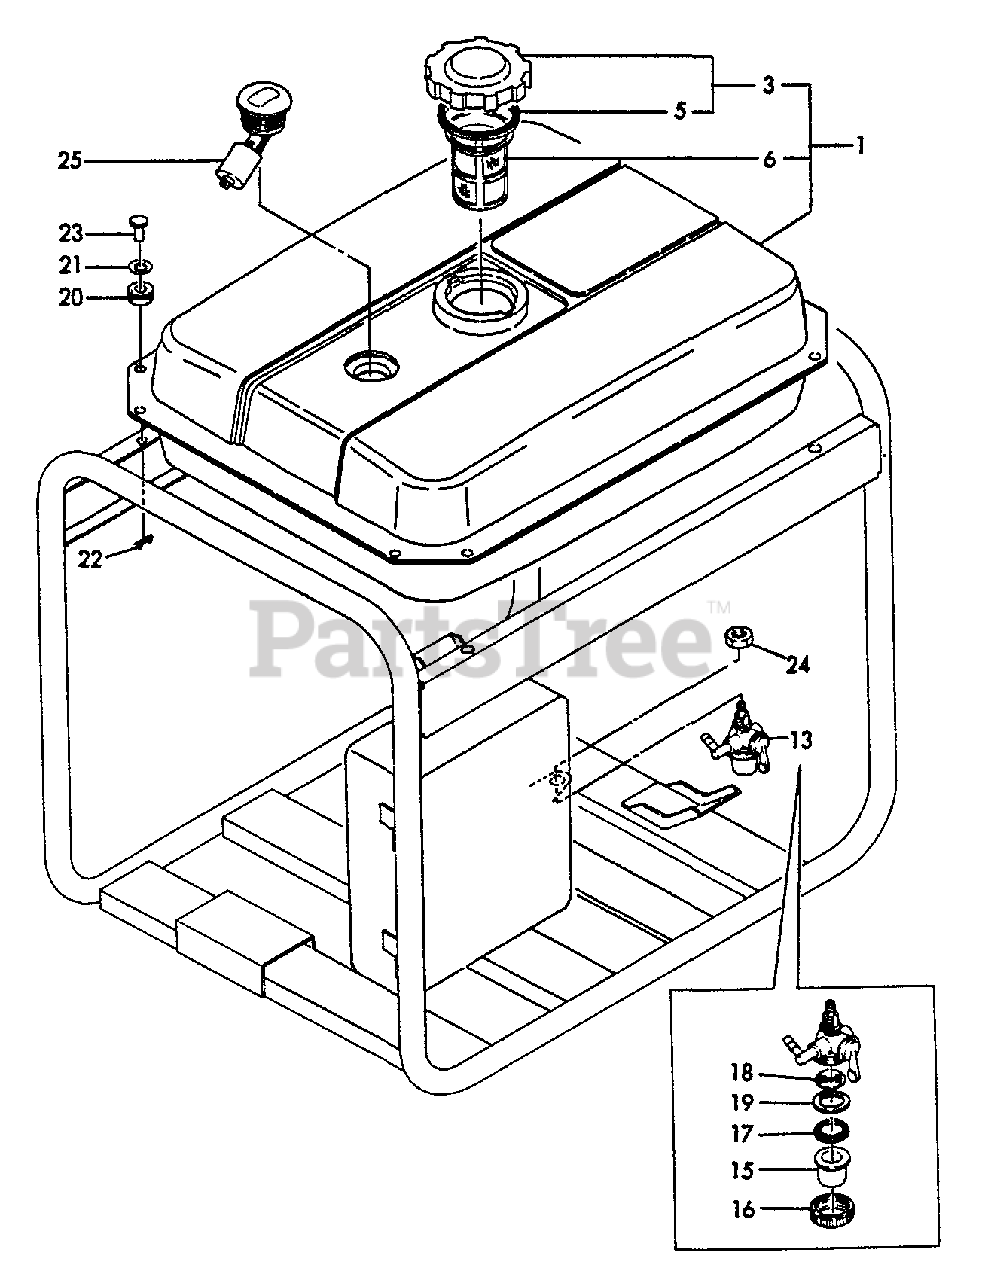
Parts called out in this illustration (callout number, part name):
1	FUEL TANK ASSY
3	CAP ASSY
5	GASKET
6	STRAINER, FUEL
13	FUEL COCK ASSY
15	BOWL, STRAINER
16	RETAINER
17	GASKET
18	FILTER, FUEL
19	PLATE
20	GROMMET
21	WASHER
22	PIN - 6 -- SNAP
23	PIN M6×14
24	LOCKNUT - 12
25	GAUGE, FUEL
